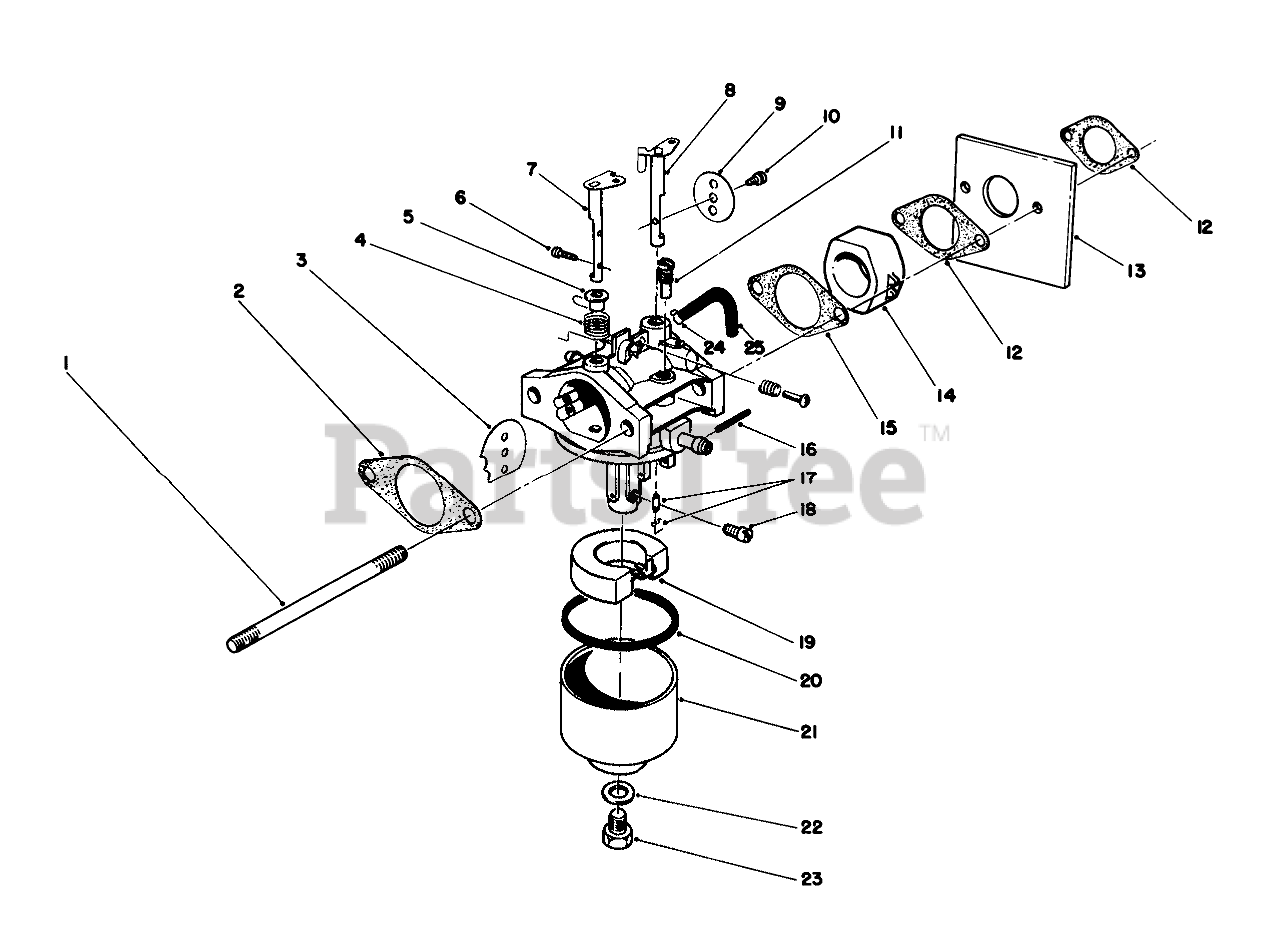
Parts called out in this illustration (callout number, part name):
1	STUD-CARBURETOR
2	GASKET-AIR CLEANER
3	PLATE
4	SPRING
5	BUSHING
6	SCREW
7	SHAFT-CHOKE
8	SHAFT
9	PLATE
10	Screw-Throttle
11	PILOT JET
12	GASKET
13	SHIELD-CARBURETOR
14	INSULATOR-CARBURETOR
15	Clamp
16	Pin
17	NEEDLE
18	JET-MAIN
19	FLOAT
20	GASKET
21	Bowl-Float
22	GASKET
23	Bolt
24	CLAMP
25	VENT TUBE
